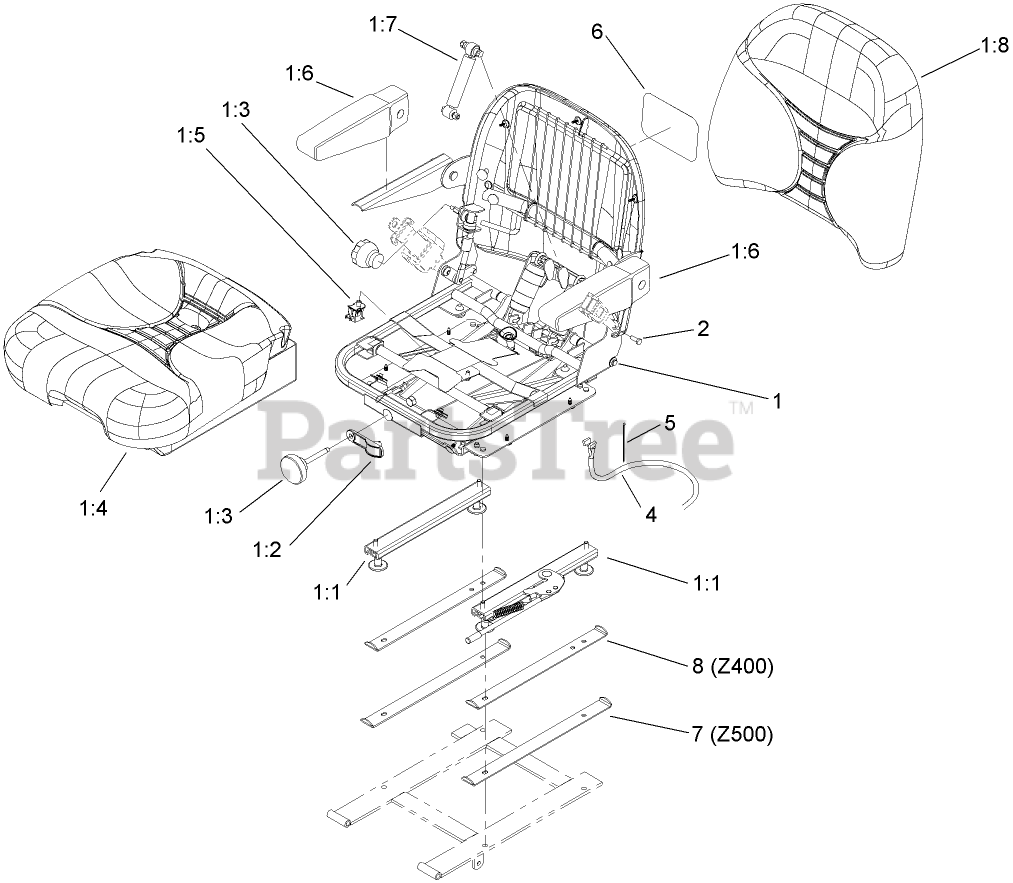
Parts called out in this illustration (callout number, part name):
1	SEAT-SUSPENSION
1:1	Seat Track Kit
1:2	Weight Indicator Kit
1:3	Knob Kit
1:4	Bottom Cushion Kit
1:5	SWITCH-BAIL
1:6	PAD-ARMREST
1:7	Shock Absorber Kit
1:8	CUSHION-BACK
2	SCREW-HH
4	HARNESS-WIRING, SEAT
5	TIE-PLASTIC
6	DECAL
7	STOP-SEAT
8	STOP/SPACER-SEAT
